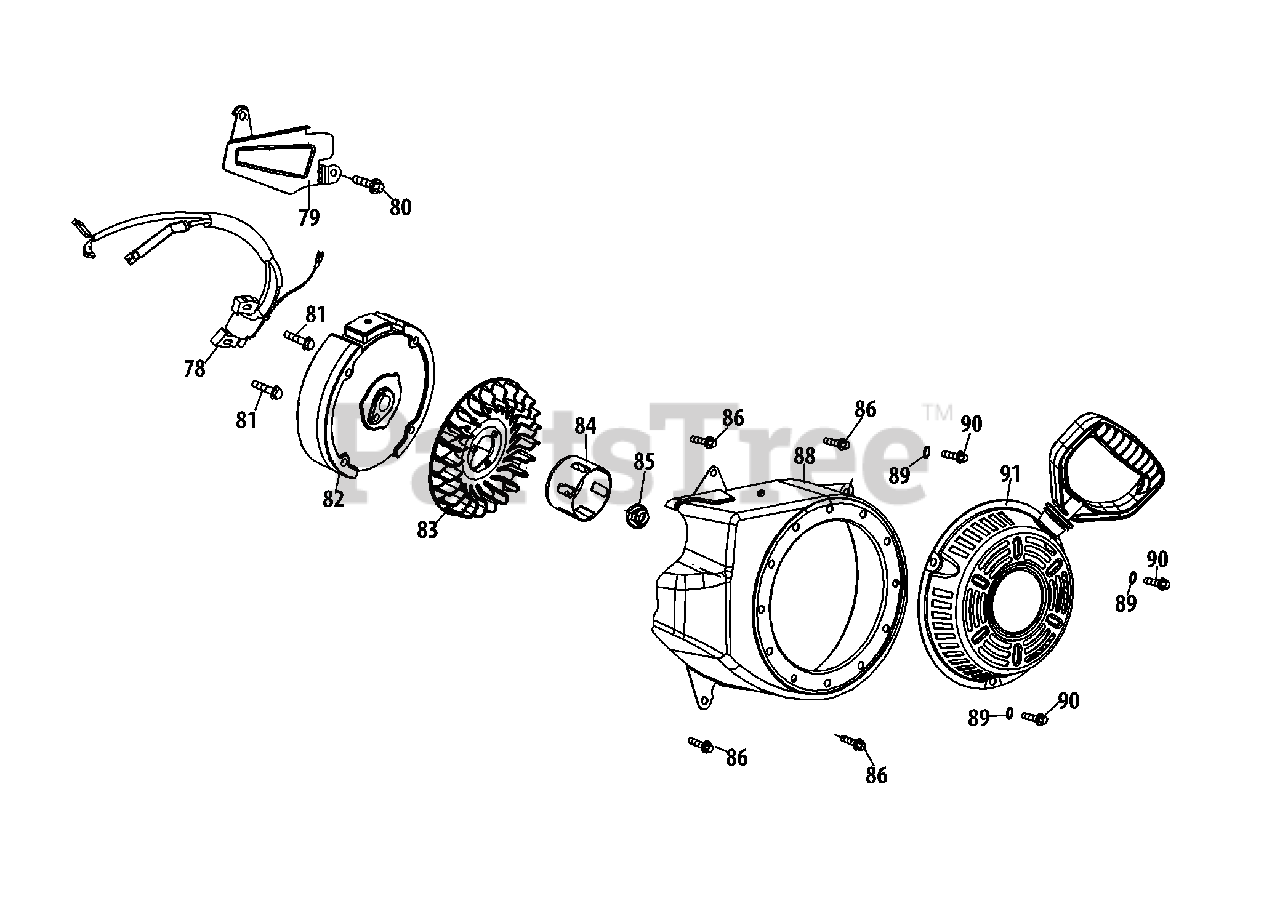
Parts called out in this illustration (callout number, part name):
78	Ignition Coil Assembly
79	Air Flow Shield
80	Bolt M6×10
81	Bolt M6×25
82	Flywheel
83	Cooling Fan
84	Starter Cup
85	Flywheel Nut, M14×1.5
86	Bolt M6×12
88	Blower Housing
89	Washer 6
90	Bolt M6×10
91	Recoil Starter Assembly
